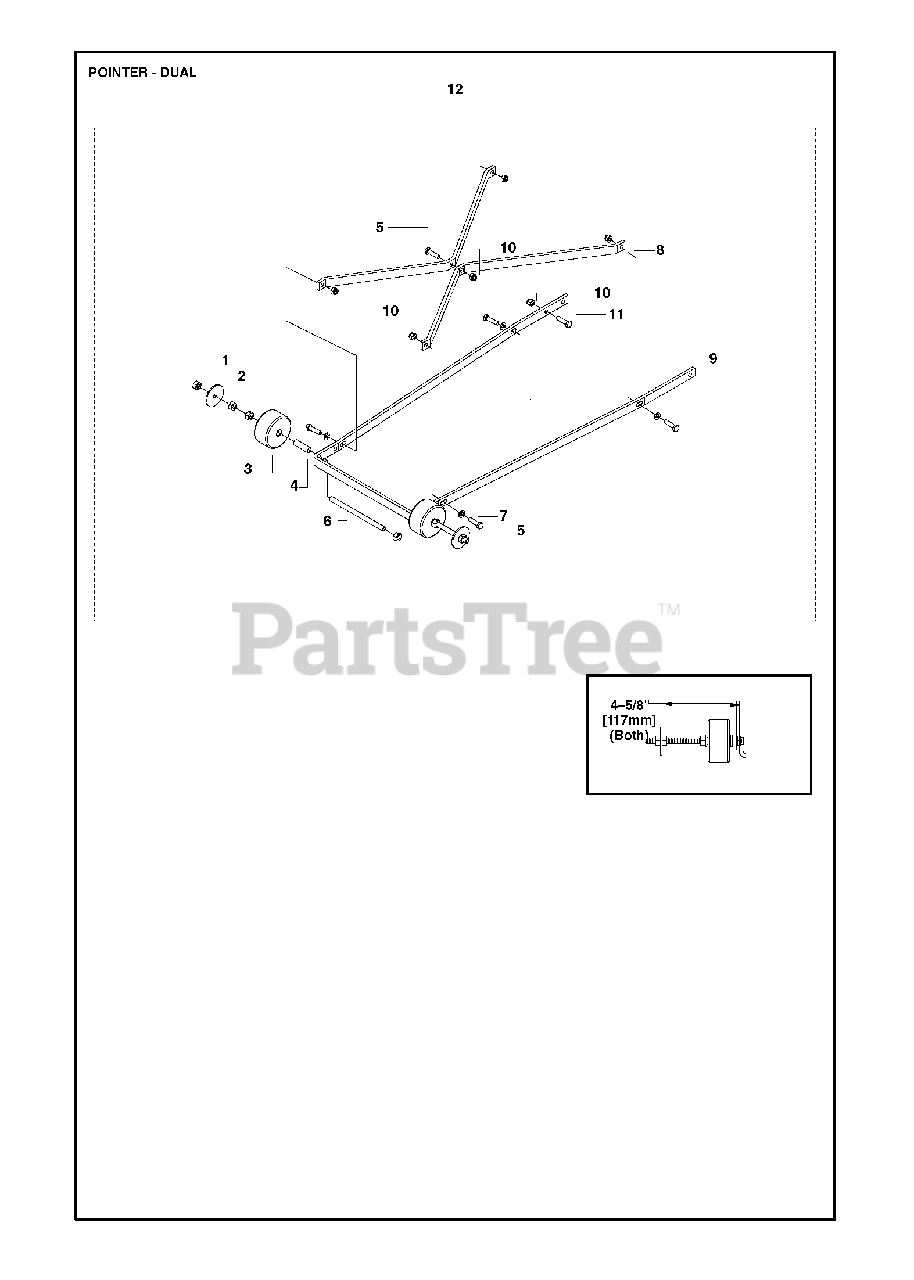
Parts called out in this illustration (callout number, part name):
7	WASHER
9	BAR. OUTSIDE. FINISHED
10	HEXAGON LOCKING NUT
